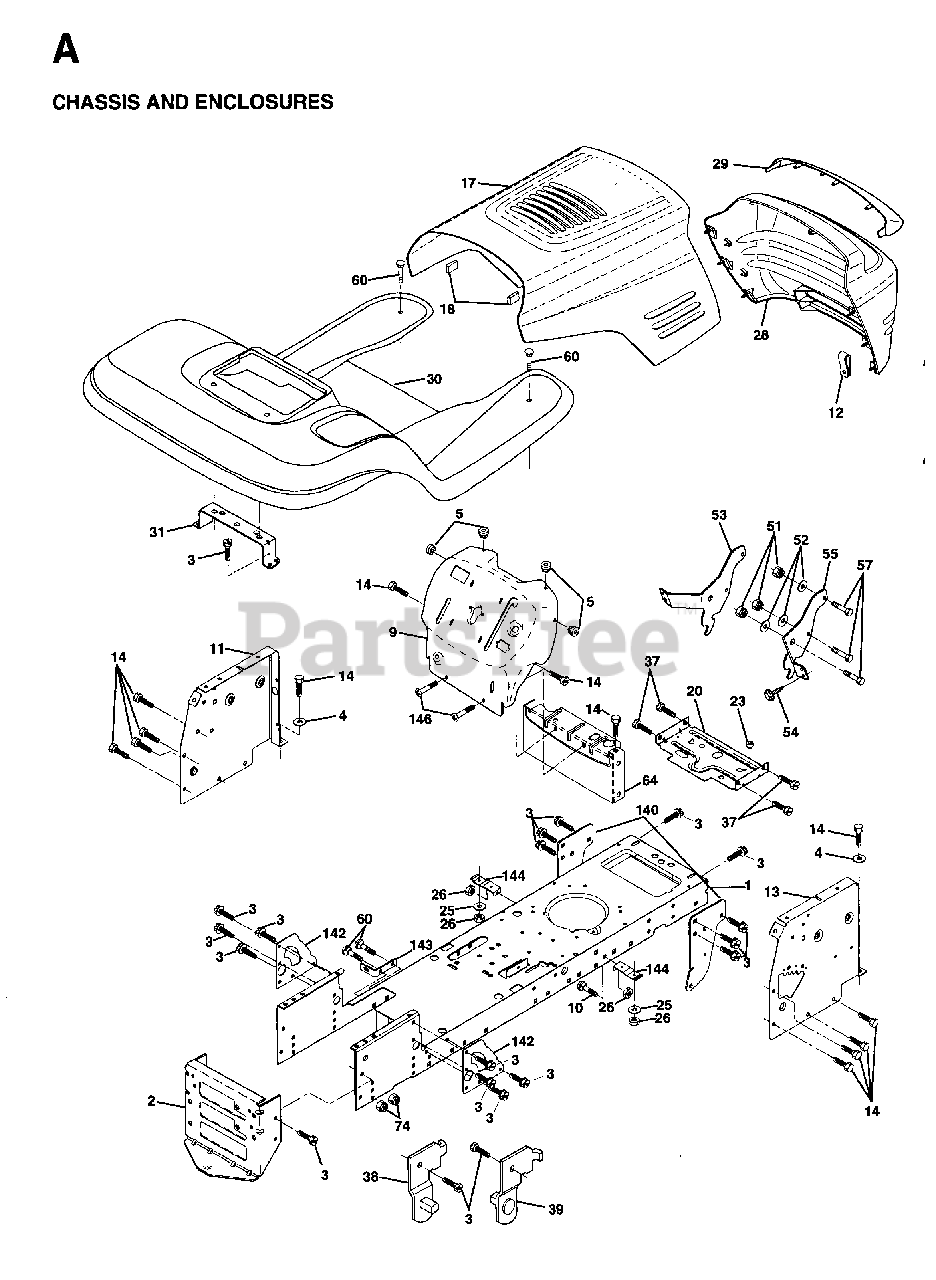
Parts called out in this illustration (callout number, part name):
1	CHASSIS WELDMENT
2	STRETCH DRAWBAR
3	SCREW
5	BUMPER.RUBBER.HOOD
10	BOLT D
11	PANEL PNT DASH LH
13	PANEL DASH RH
14	SCREW LT
18	BUMPER HOOD T
20	PLATE MTG
23	GROMMET T
25	WASHER
26	NUT
37	SCREW LT
38	BRACKET LH PIVOT
39	BRACKET RH PIVOT
51	LOCKNUT
52	WASHER
57	BOLT
64	DASH LOWER
74	LOCKNUT
140	BRACKET CHASSIS FRONT
142	PLATE REINFORCEMENT
143	BRACKET, SWAY BAR
144	BRACKET FOOTREST
146	SCREW TORX HD 5/16X18
